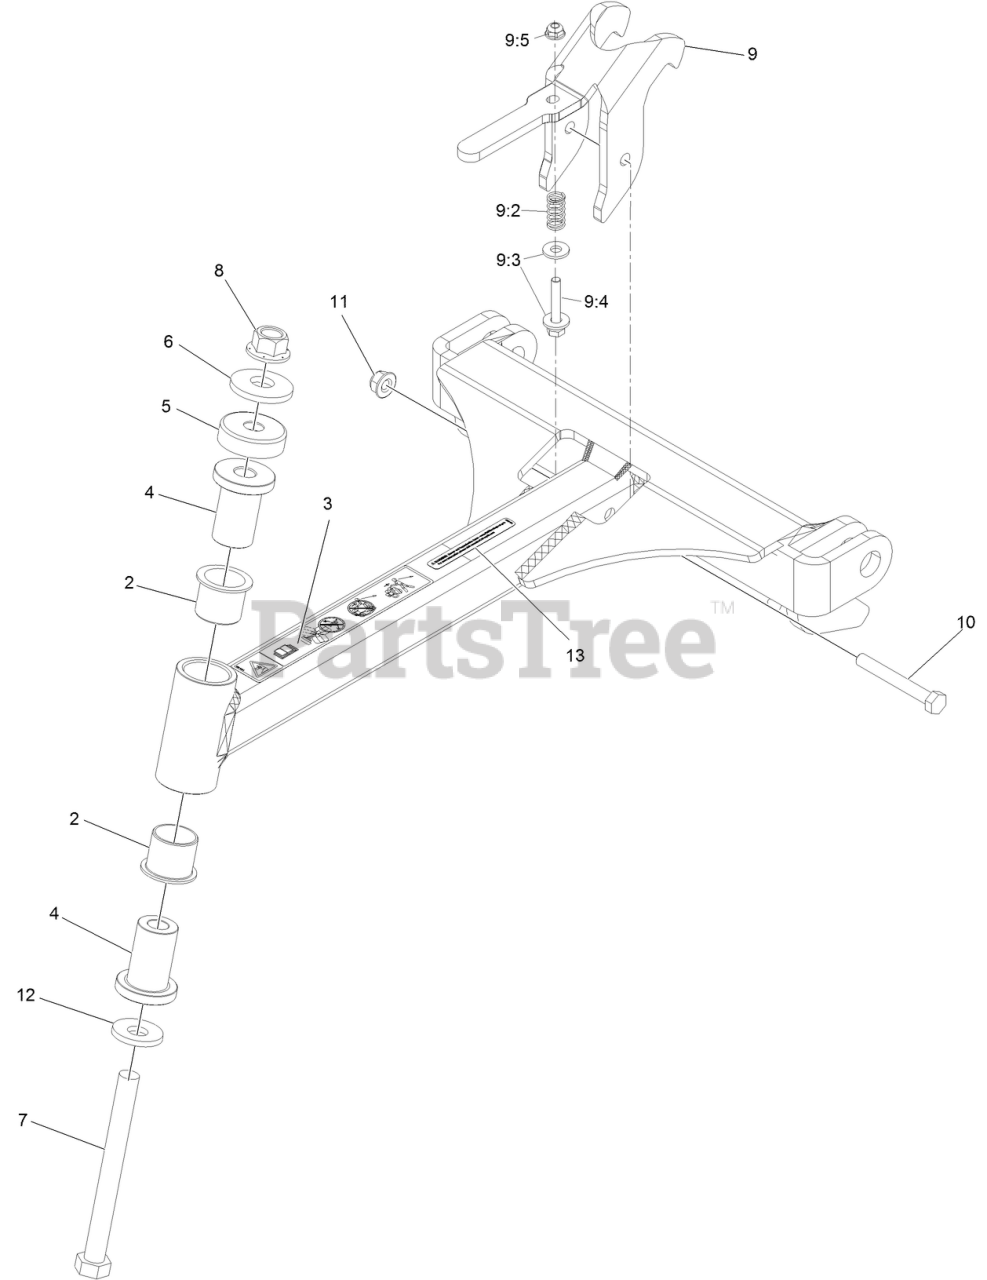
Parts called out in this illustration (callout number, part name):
2	BUSHING-PIVOT
3	DECAL-SULKY HAZARD
4	SPACER, PIVOT
5	COVER, DUST
6	WASHER-BELLEVILLE
7	SCREW-HH
8	Nut-Lock 1/2-13
9	TRANSPORT LATCH ASM
9:2	SPRING, COMPRESSION
9:3	WASHER-FLAT
9:4	SCREW-HH
10	SCREW-HH
11	NUT-HF, NI
12	WASHER-SPRING
13	DECAL-WARNING
